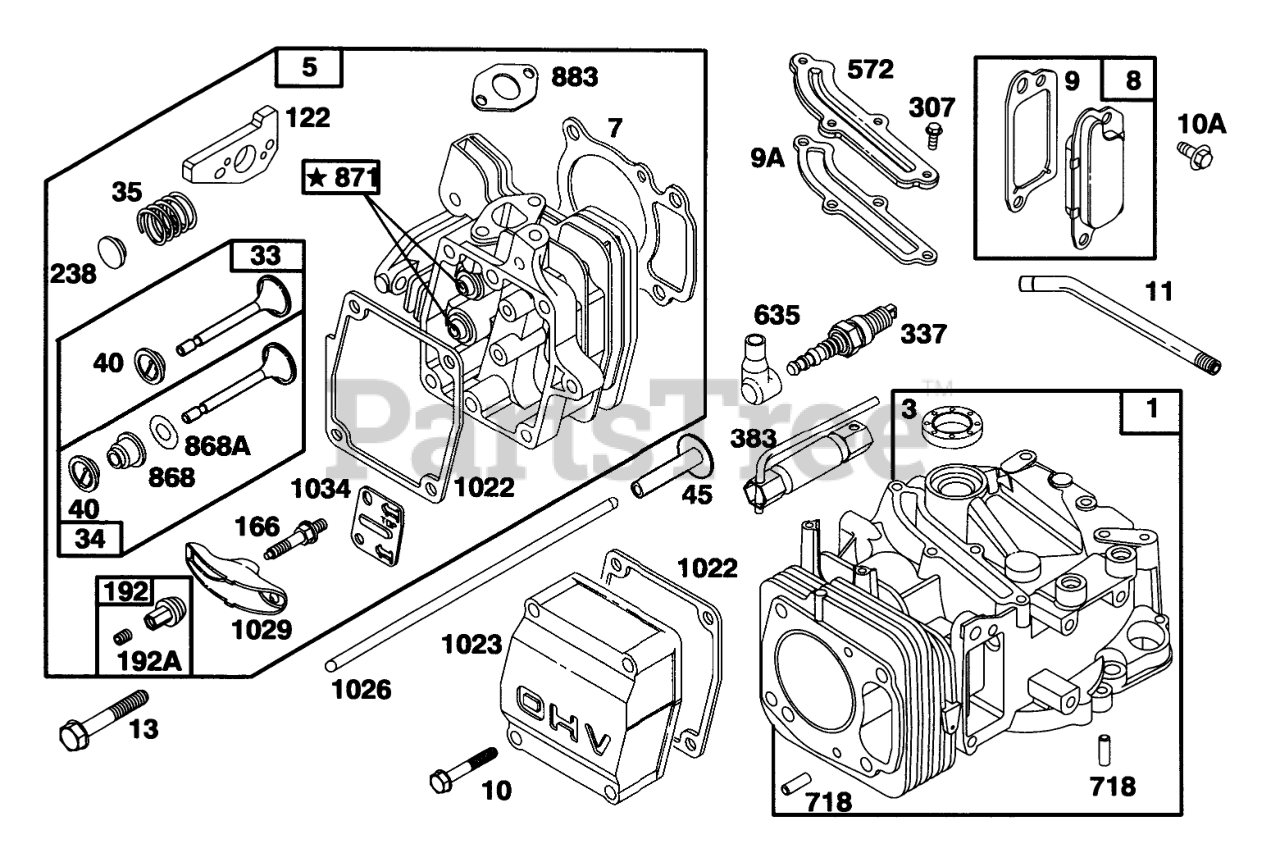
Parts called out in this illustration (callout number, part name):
1	CYLINDER ASSEMBLY
3	SEAL - OIL
5	CYLINDER HEAD
7	CYLINDER HEAD GASKET
8	Breather Assy
9	BREATHER GASKET
9A	GASKET-BREATHER
10	HEX HEAD SCREW
10A	HEX HEAD SCREW
11	TUBE - BREATHER
13	PLUG - PIPE
33	EXHAUST VALVE
34	INTAKE VALVE
35	VALVE SPRING
40	SPRING RETAINER
45	VALVE TAPPET
122	ADAPTER ASSEMBLY
166	ROCKER ARM STUD
192	NUT - HEX SPECIAL
192A	SCREW SET
238	VALVE CAP
307	SCREW - SEM
337	PLUG-SPARK
383	WRENCH-SPARK PLUG
572	BAFFLE - CYCLINDER
635	SPARK PLUG ELBOW
718	DOWEL - SLEEVE
868	ASM - VALVE SEAL
868A	Seal-Valve
871	Bushing-Guide
883	EXHAUST GASKET
1022	ROCKER COVER GASKET
1023	COVER - VALVE
1026	PUSH ROD
1029	ROCKER ARM
1034	PUSH ROD GUIDE
